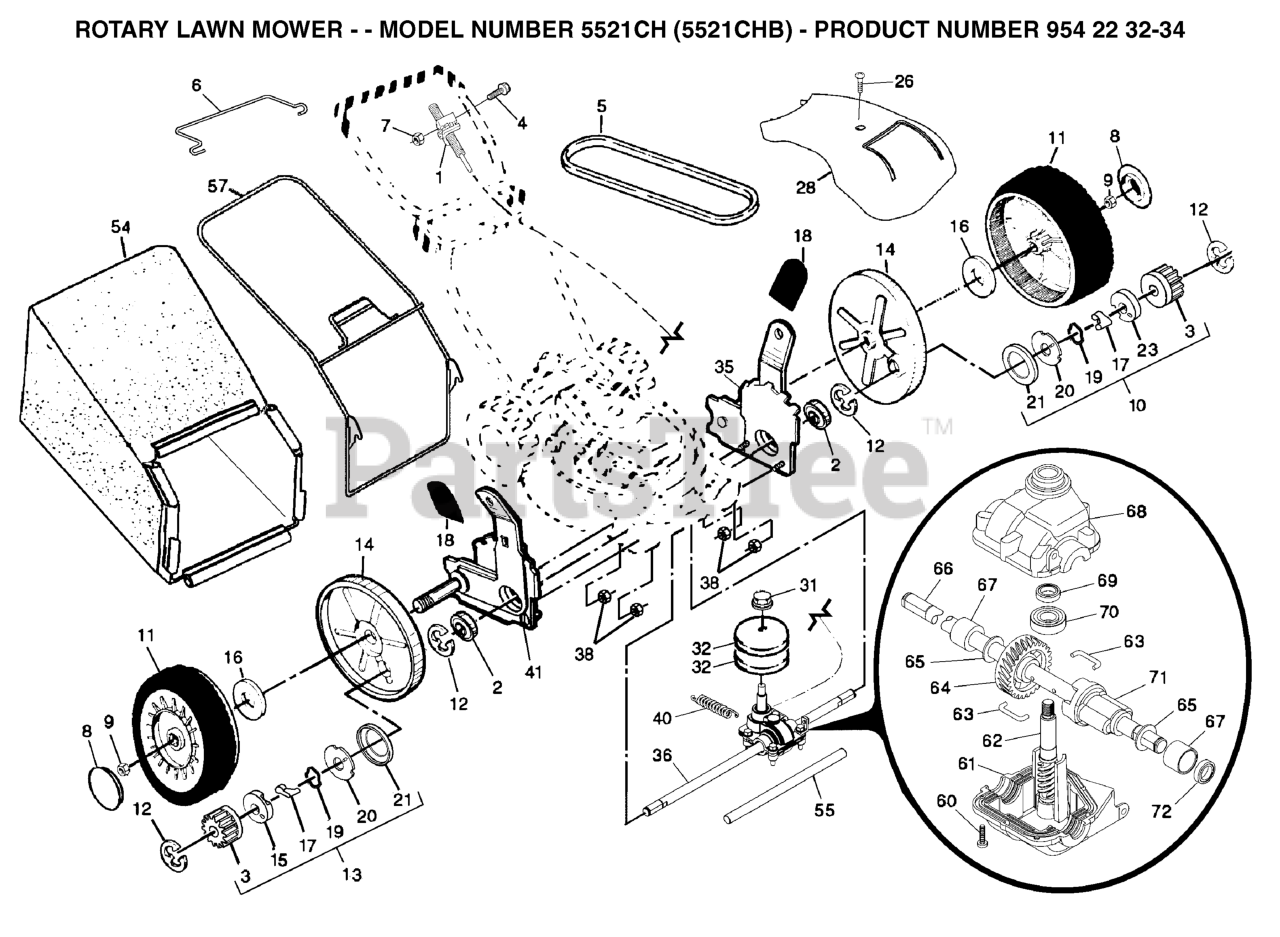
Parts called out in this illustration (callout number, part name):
1	VARI-SPEED DRIVE CONTROL ASSEM
2	BEARING, BALL
3	GEAR, PINION
6	BAR CONTROL DRIVE
7	LOCK NUT
8	HUBCAP
9	NUT
10	PINION/PAWL ASSY LH
11	WHEEL.8X2.PR.LP.RAD.BLK
12	E-RING 7/16 RE
13	PINION/PAWL ASSY RH
14	DUST COVER, WHEEL
15	RETAINER, DRIVE, RH
16	WASHER FLUT
17	PAWL.DRIVE.21.EZ-WALK
18	SELECTOR KNOB
19	SPRING, TORSION
20	DISC.DRIVE.21.EZ-WALK
21	SEAL, FRICTION
23	RETAINER.DRIVE.21.EZ-WALK.LT
26	SCREW, HEX HD TAPPING #10-24 1
28	COVER.DRIVE.21.FWGD.GRAY
31	FLANGED LOCKNUT 3/8-16 ZINC
32	PULLEY
35	KIT.ADJUSTER.ASM.EZ.LH
36	TRANSMISSION.21RD.FGDE
38	LOCKNUT.NYLOC.1/4-20
40	SPRING, RETURN
41	KIT.ADJUSTER.ASM.EZ(169770).RT
54	GRASS BAG
55	DRIVESHAFT COVER
57	FRAME.GBAG.21.HT/BAG
61	LOWER CASE
62	SHAFT INPUT (13056)
63	WIRE, FORMED (15966)
64	GEAR.27.TEETH.WALK.MOWER
66	SHAFT OUTPUT (12198)
68	UPPER CASE
69	SEAL INPUT SHAFT
72	SEAL.OUTPUT.SHAFT
